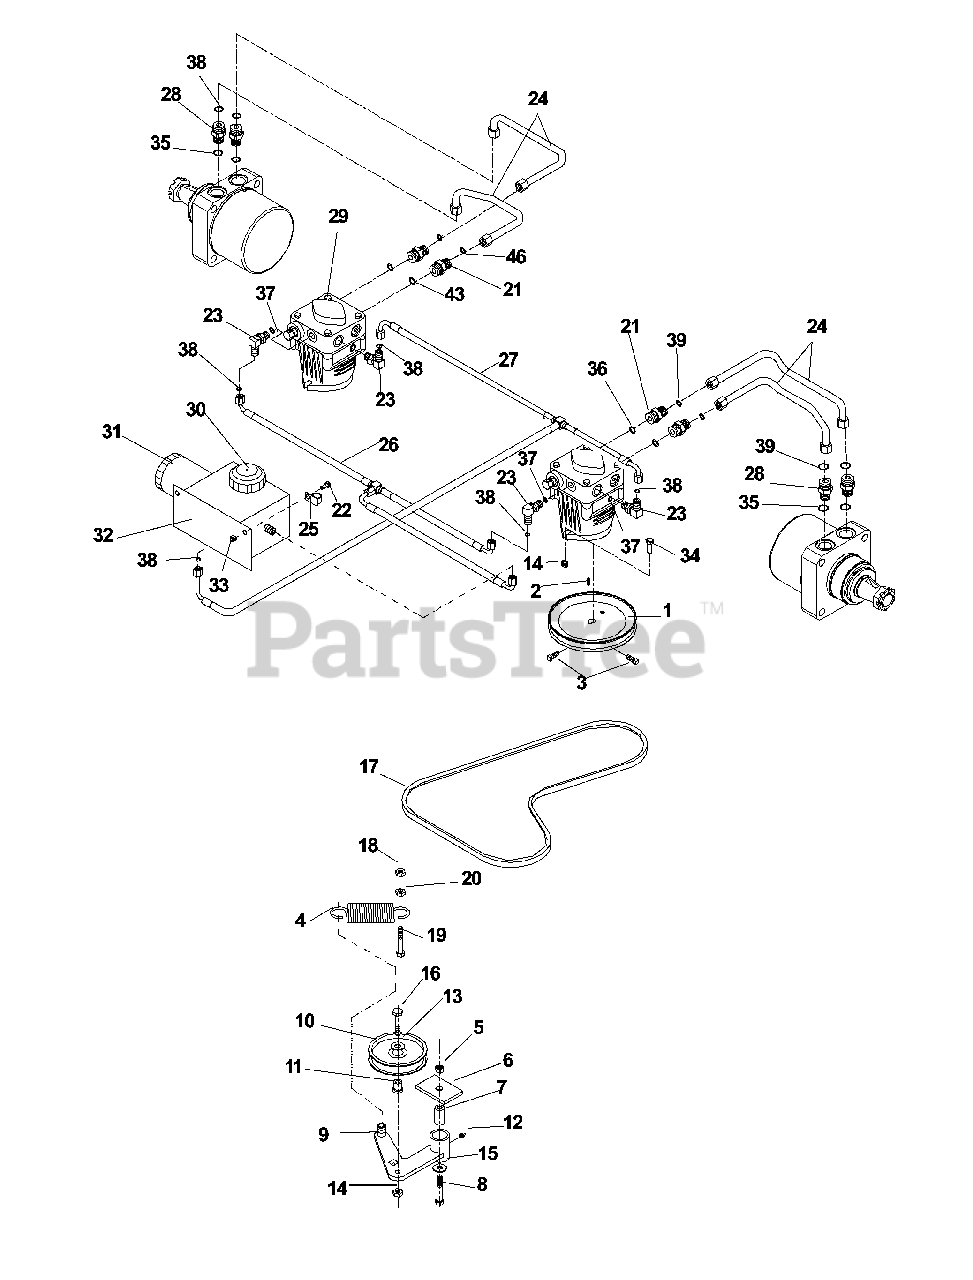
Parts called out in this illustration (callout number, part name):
2	KEY 5 MM SQ X 25 MM
3	SCREW 5/16C X 5/8 SQ HEAD
5	NUT 1/2-13 HEX NYLOC ZD
7	PIVOT BUSHING
8	HCS 1/2C X 3 1/4
9	IDLER ARM WLDT
10	IDLER PULLEY
11	BUSHING, IDLER FLANGE
12	ZERK
13	WASHER 3/8 FLAT
14	NUT 3/8C CENTERBLOCK
15	WASHER 1/2 FLAT
16	HCS 3/8-16 X 1 3/4 GR5
17	PUMP BELT
18	NUT 3/8-16 NYLOC
19	HCS 3/8C X 2
20	NUT 3/8C WHIZ
21	FITTING, STRAIGHT F6400-8-8-0
22	HCS 5/16C X 3/4
23	ELBOW, F6801-6-6-0 90 DEGREE
24	HYDRAULIC HOSE
25	LOOM CLIP
26	T-ASSEMBLY
27	T-ASSEMBLY
28	FITTING
29	10CC PUMP W/RTN'S
30	HYDRAULIC CAP
31	HYDRAULIC OIL FILTER
32	RESERVOIR W/CAP & FILTER
33	NUT 5/16 NYLOC
34	HCS 3/8C X 1 SERRATED HEAD
